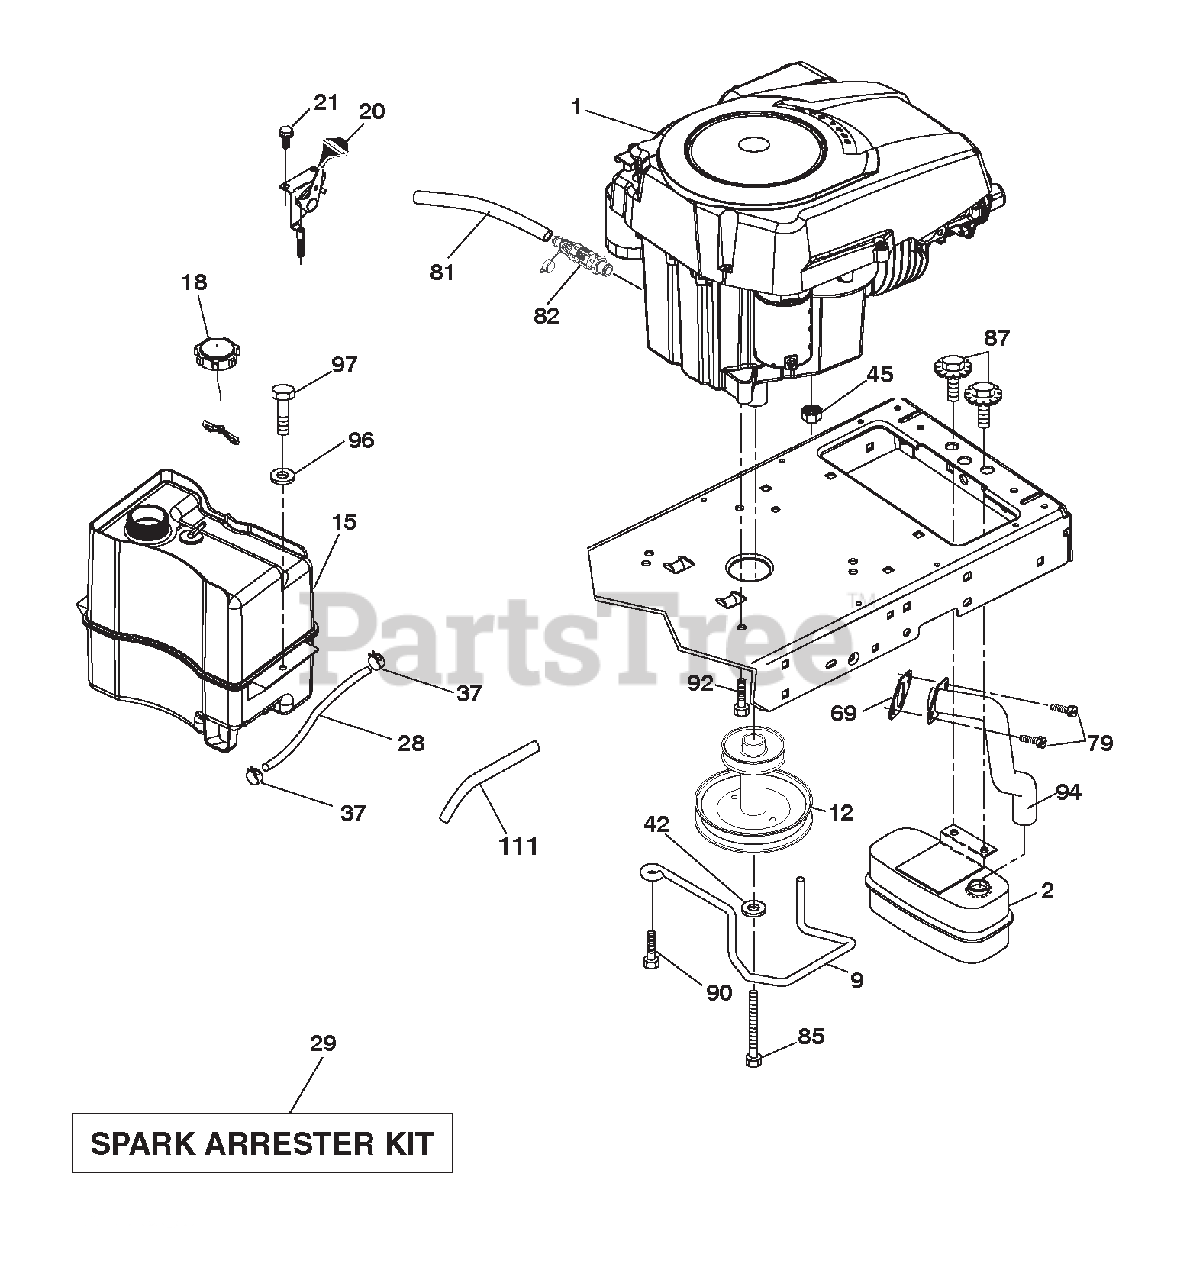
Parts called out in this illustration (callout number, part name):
1	ENGINE KOHL MODEL NO. SV620-3222 (581797301)(ORDER PARTS FROM ENGINE MANUFACTURER.)
2	MUFFLER
9	KEEPER BELT ENGINE
12	PULLEY.ENGINE.5.0.P.D.
15	TANK.FUEL.2.5.GAL.
18	CAP.FUEL
20	CONTROL THROTTLE/CHOKE
28	LINE.FUEL.20"
29	KIT.SPARK ARRESTOR(392390 B&S)
37	CLAMP.HOSE.BLK.
42	WASHER.LOCK.HVY HLCL.SPR.7/16
45	Nut, Keps Hex 1/4-20 unc
69	GASKET.KOHLER.SV.I.
79	SCREW SOCKET HEAD 5/16-18 X 1
81	TUBE.DRAIN.OIL.EASY
82	VALVE OIL DRAIN
85	BOLT.HEX.7/16-20X4XGR5-1.5THR.
87	BOLT.5/16-18 UNC X 1 W/SEMS.BL
90	SCREW.3/8-16X1.SMGML.TAP/R.BLK
92	SCREW.3/8-16 X 1.SMGML.TAP/R
94	TUBE.EXHAUST.KOHL.COURAGE
96	WASHER.9/32 X 7/8 X 16GA.
97	SCREW.HEXWSH.THDROL.1/4-20X3/4
111	PURGE.LINE.CARB
